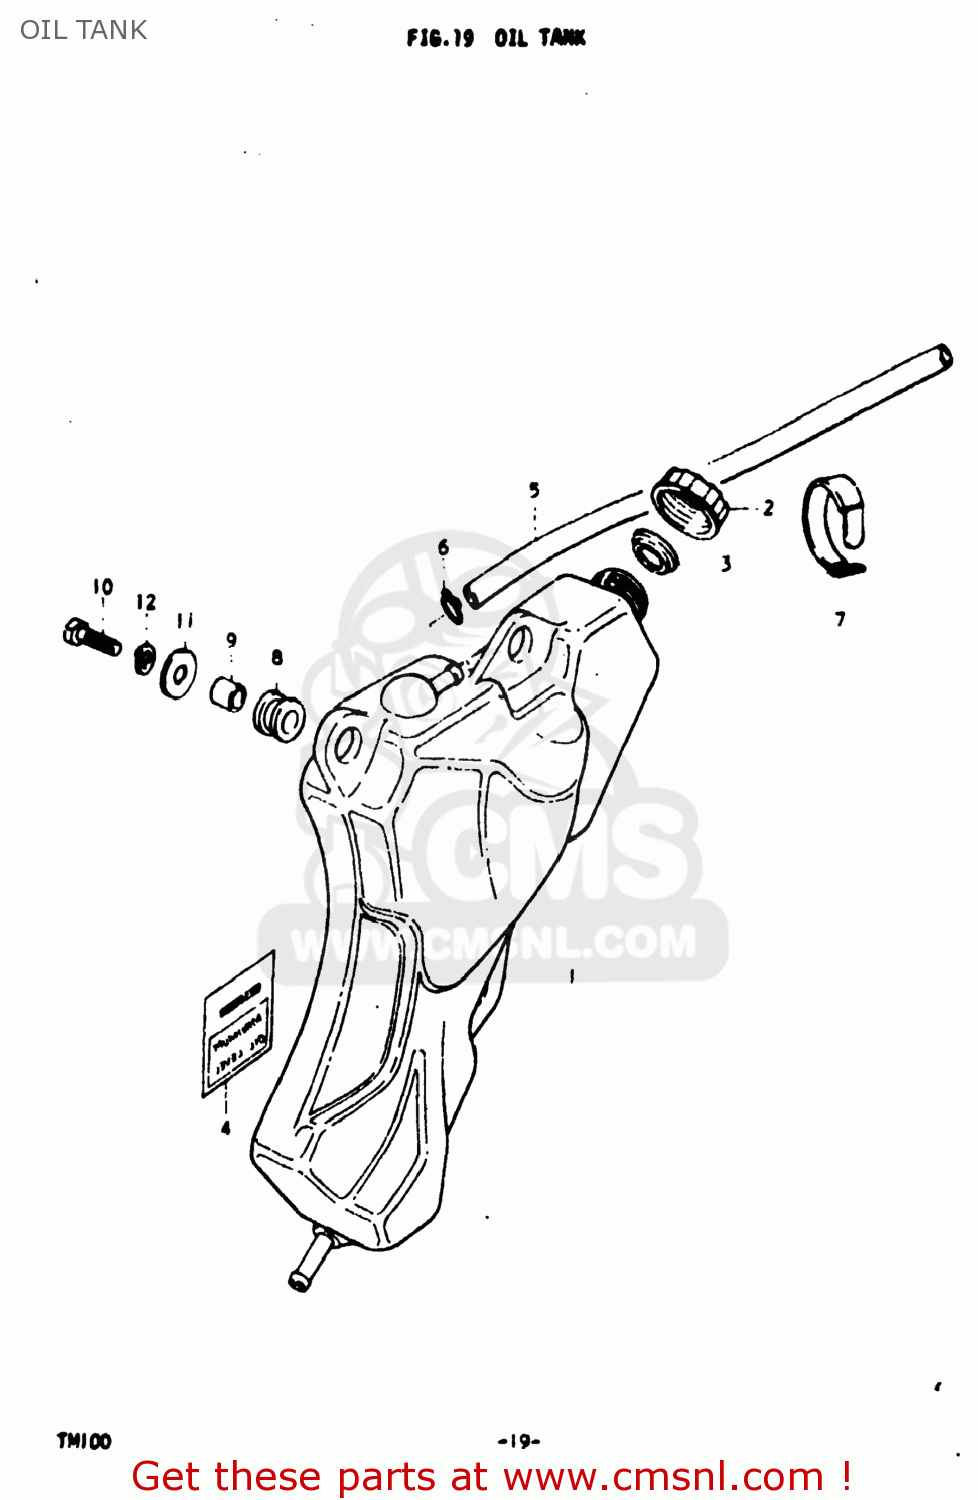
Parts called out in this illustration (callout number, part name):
1	TANK,OIL
2	CAP, OIL TANK
3	GASKET,OIL TANK (NAS)
4	LABEL
5	HOSE
6	CLIP
7	CLAMP
8	CUSHION
9	SPACER (6.8X10X10)
10	BOLT
11	WASHER (6.5X20X1.2)
12	LOCK WASHER
